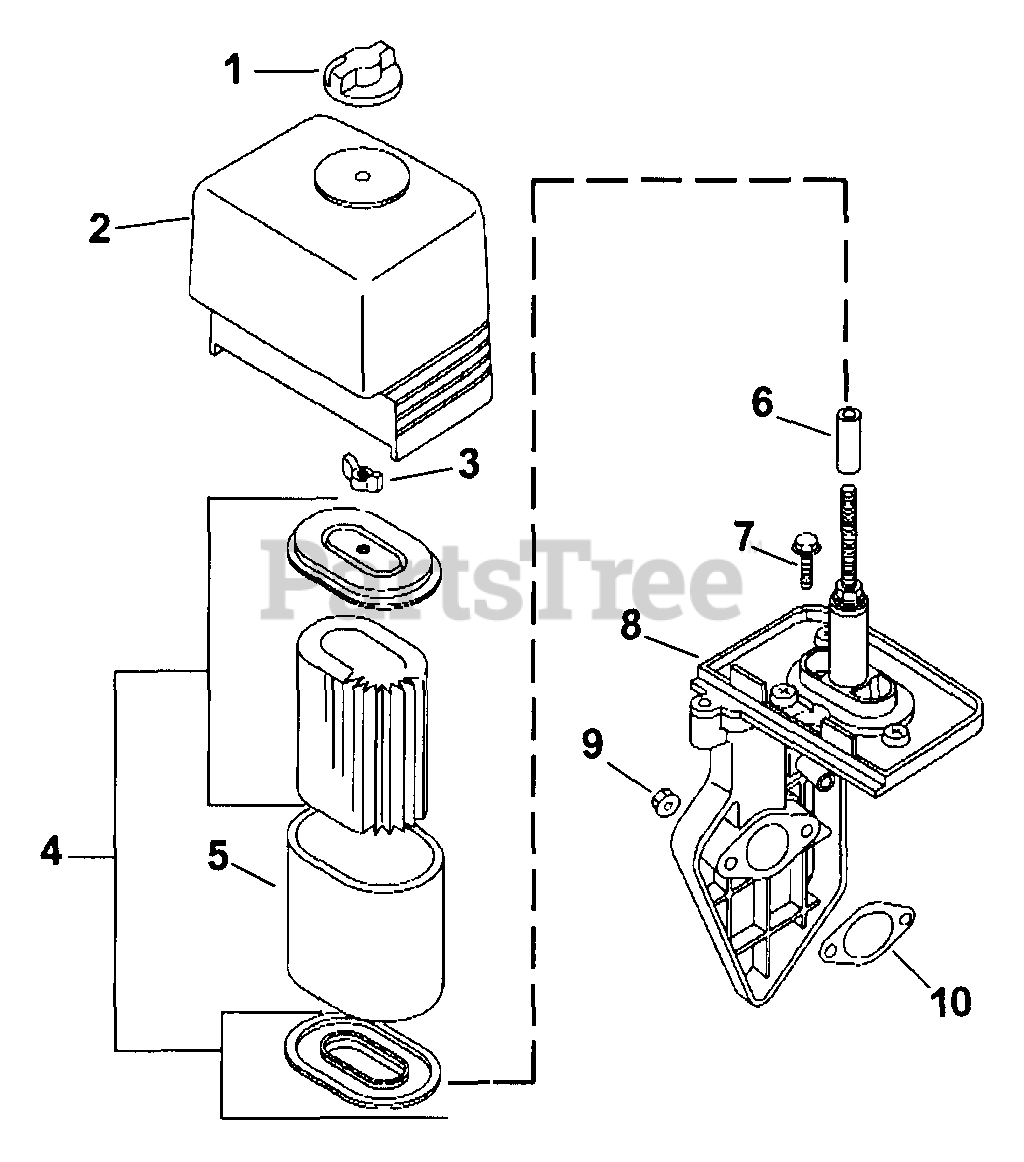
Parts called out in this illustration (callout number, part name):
1	NUT-(#DSC)
2	COVER,A/C
3	NUT, WING A/C
5	PRECLEANER, ELEMENT
8	BASE, A/C
10	GASKET A/C
